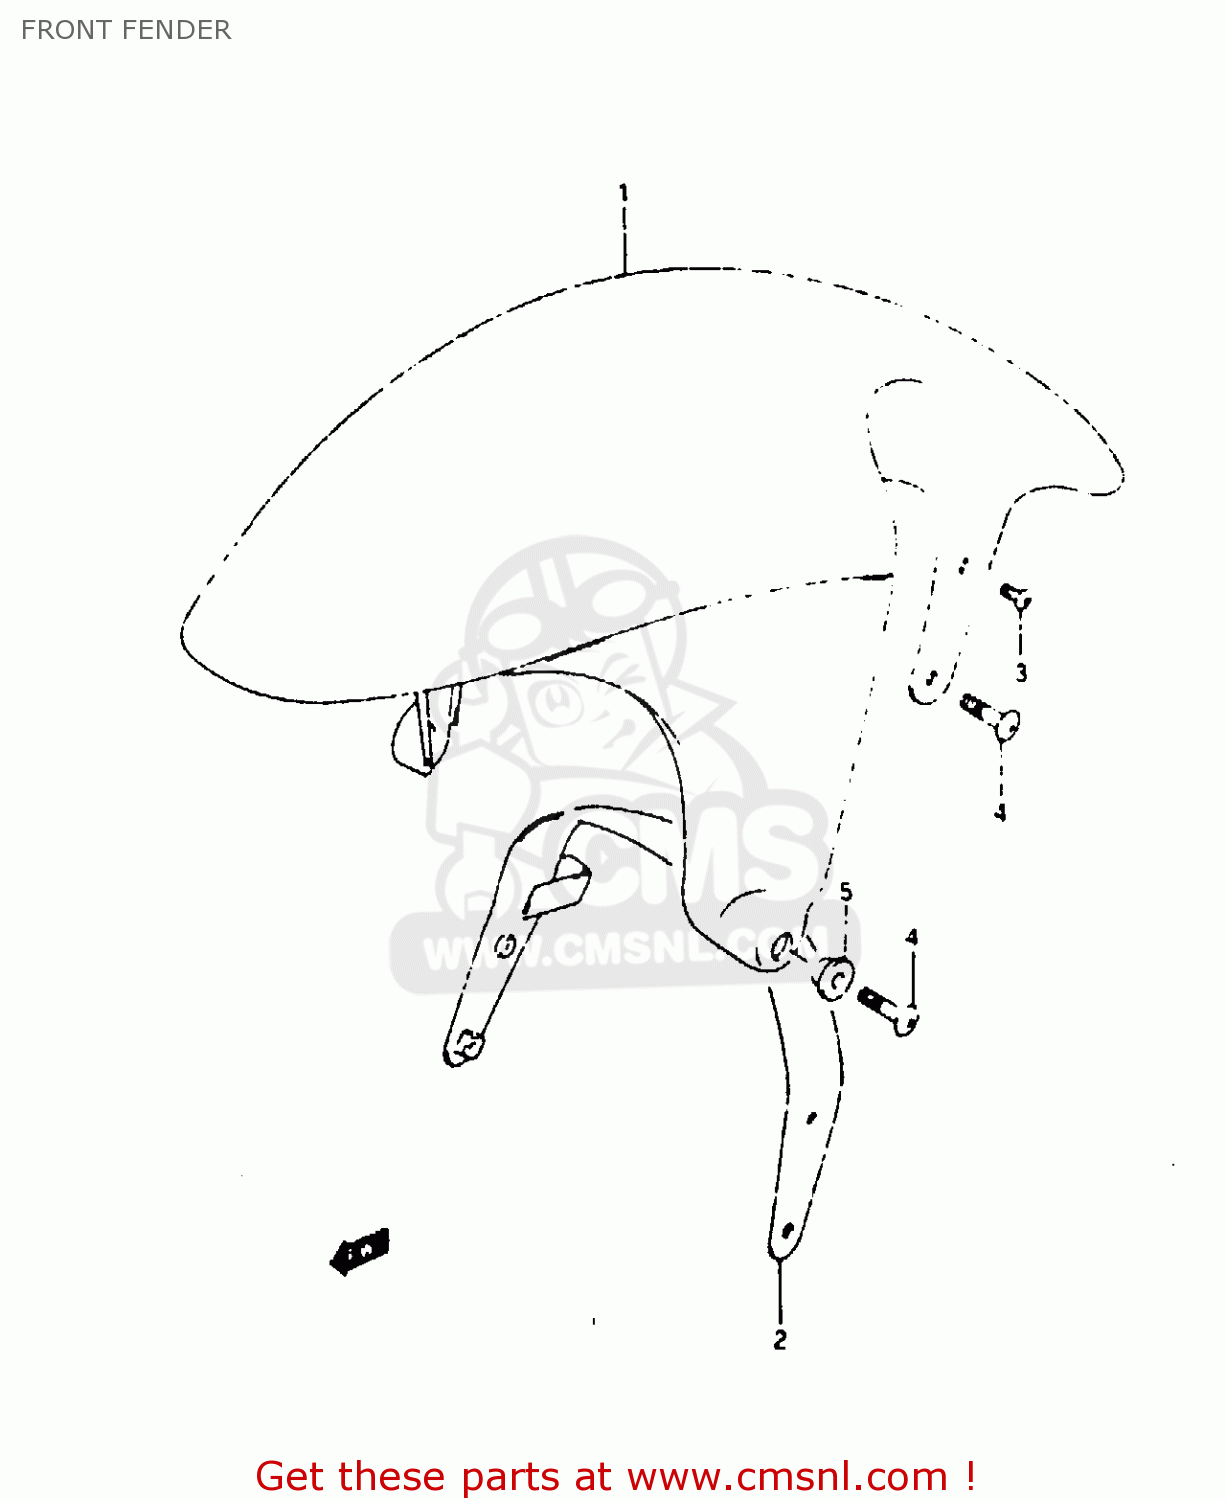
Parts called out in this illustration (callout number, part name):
1	FENDER,FR
2	BRACE,FR FENDER RR
3	SCREW
4	SCREW(6X20)
5	WASHER(6.3X16X1.5)
